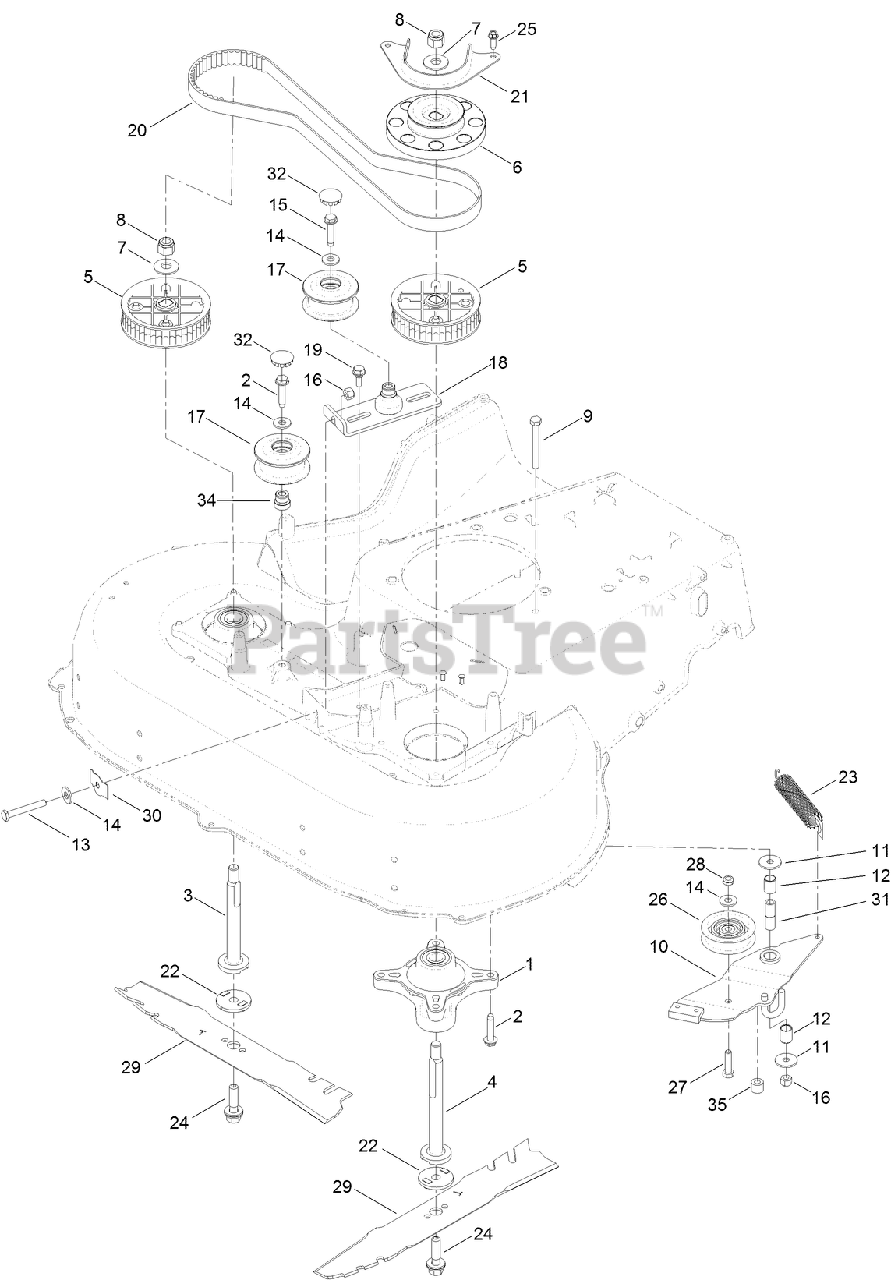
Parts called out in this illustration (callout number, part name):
1	SPINDLE ASM
3	SHAFT-SPINDLE
4	SHAFT-SPINDLE
5	SPROCKET
6	PULLEY-BRAKE, SPINDLE
7	WASHER-SPRING
8	NUT-HEX
9	SCREW-HH
10	BRAKE ARM ASM
11	WASHER-PIVOT
12	Bushing-Sleeve
13	BOLT-TAP, HH
14	WASHER-FLAT
15	SCREW-HH
16	NUT-LOCK, NI
17	FLAT IDLER PULLEY ASM
18	BRACKET-IDLER
19	SCREW-SHOULDER, HHF
20	BELT-SYNCHRONOUS
21	GUIDE-BELT, SPINDLE
22	ADAPTER-BLADE
23	SPRING-EXTENSION, BRAKE
24	BOLT-BLADE
25	SCREW-HWHTF
26	PULLEY-IDLER
27	SCREW-HH
28	NUT-LOCK, NI
29	BLADE-ROTARY
30	SPRING-FLAT
31	Spacer-Brake
32	PLUG-BUTTON
34	ADAPTER-BORE
35	HOSE-COOLANT
